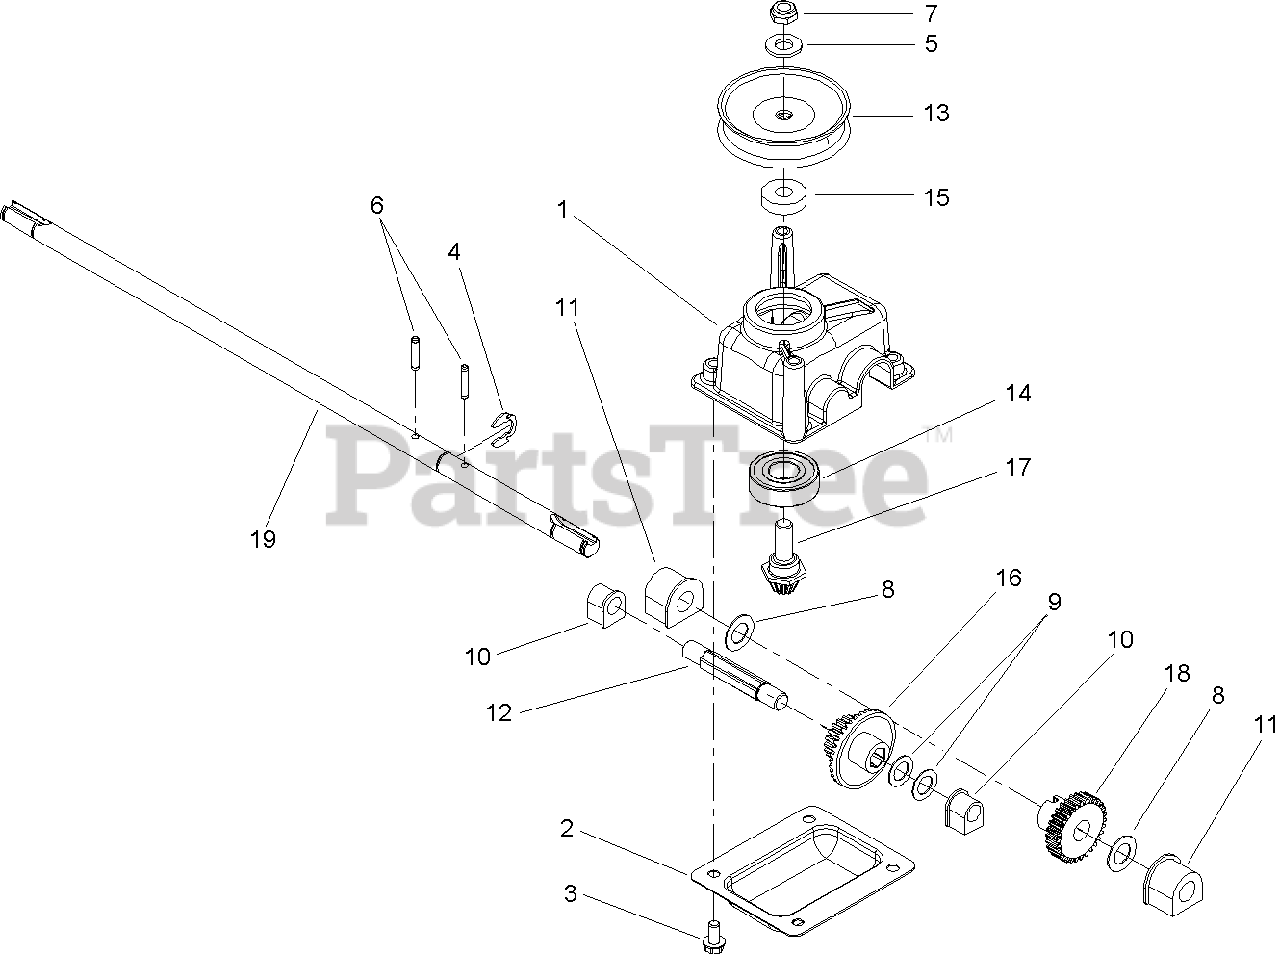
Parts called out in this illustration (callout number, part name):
1	CASE-GEAR
2	COVER-CASE, GEAR
3	SCREW-HWH
4	RING-RETAINING
5	WASHER-FLAT
6	PIN-GROOVE
7	NUT-LOCK, NI
9	WASHER-THRUST
12	SHAFT-INTERMEDIATE
13	HALF-PULLEY
14	BEARING-BALL
16	GEAR-19T SPUR, 37T BEVEL
17	GEAR-PINION, BEVEL
19	SHAFT-OUTPUT
